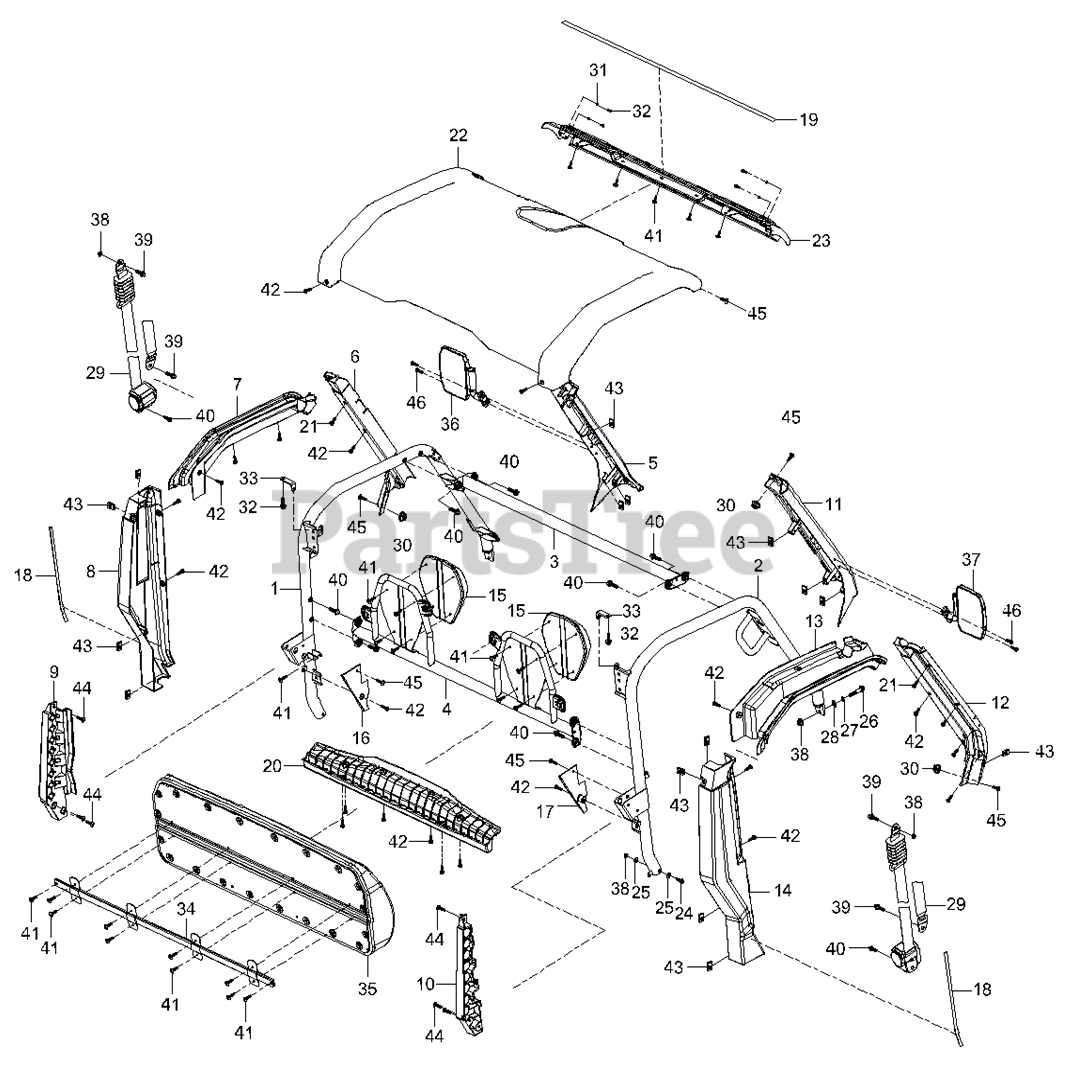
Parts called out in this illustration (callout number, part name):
1	LEFT SUPPORT FRAME KIT
2	RIGHT SUPPORT FRAME KIT
3	FRONT TOP FRAME KIT
4	REAR TOP FRAME KIT
5	A POST TOP COVER - LEFT
6	A-PILLAR PANEL (LH)
7	TOP - LEFT PROTECTOR COVER
8	B POST LEFT COVER
9	B POST - LEFT
10	B POST - RIGHT
11	A POST TOP COVER - RIGHT
12	A POST LOW COVER - RIGHT
13	TOP - RIGHT PROTECTOR COVER
14	B POST RIGHT COVER
15	HEADREST KIT
16	B POST PROTECTOR
17	B POST PROTECTOR
18	DOOR SEAL 4
19	ROOF DAMPING BAR SEAL
20	ROOF GUARD
21	SCREW ST4.2x16
22	ROOF
23	LIGHT KIT BRACKET
24	HEX NUT M10X1.25X65
25	CURVED WASHER
26	HEX FLANGE BOLT M10X1.25X50
27	SPRING WASHER
29	SEAT BELT BUCKLE ASSEMBLY
30	HEX FLANG NUT M6
31	FLAT WASHER
32	CROSS PLATE HEAD SCREW M6X12
33	BRACKET IV
34	BRACKET - BACKREST KIT
35	SEAT BACKREST KIT
36	REARVIEW MIRROR KIT - LEFT
37	REARVIEW MIRROR KIT - RIGHT
38	LOCK NUT M10X1.25
39	SHOULDER FLANGE BOLT M10X14X9X25
40	HEX FLANGE BOLT (M10x20)
41	SCREW M6X16
42	SOCKET HEX FLAT HEAD BOLT M6X16
43	CLAMP NUT M6X6
44	HEXAGON FLANGE BOLT M8X20
45	HEX HEAD CAP SCREW M6X16
46	HEX HEAD CAP SCREW M8X25
